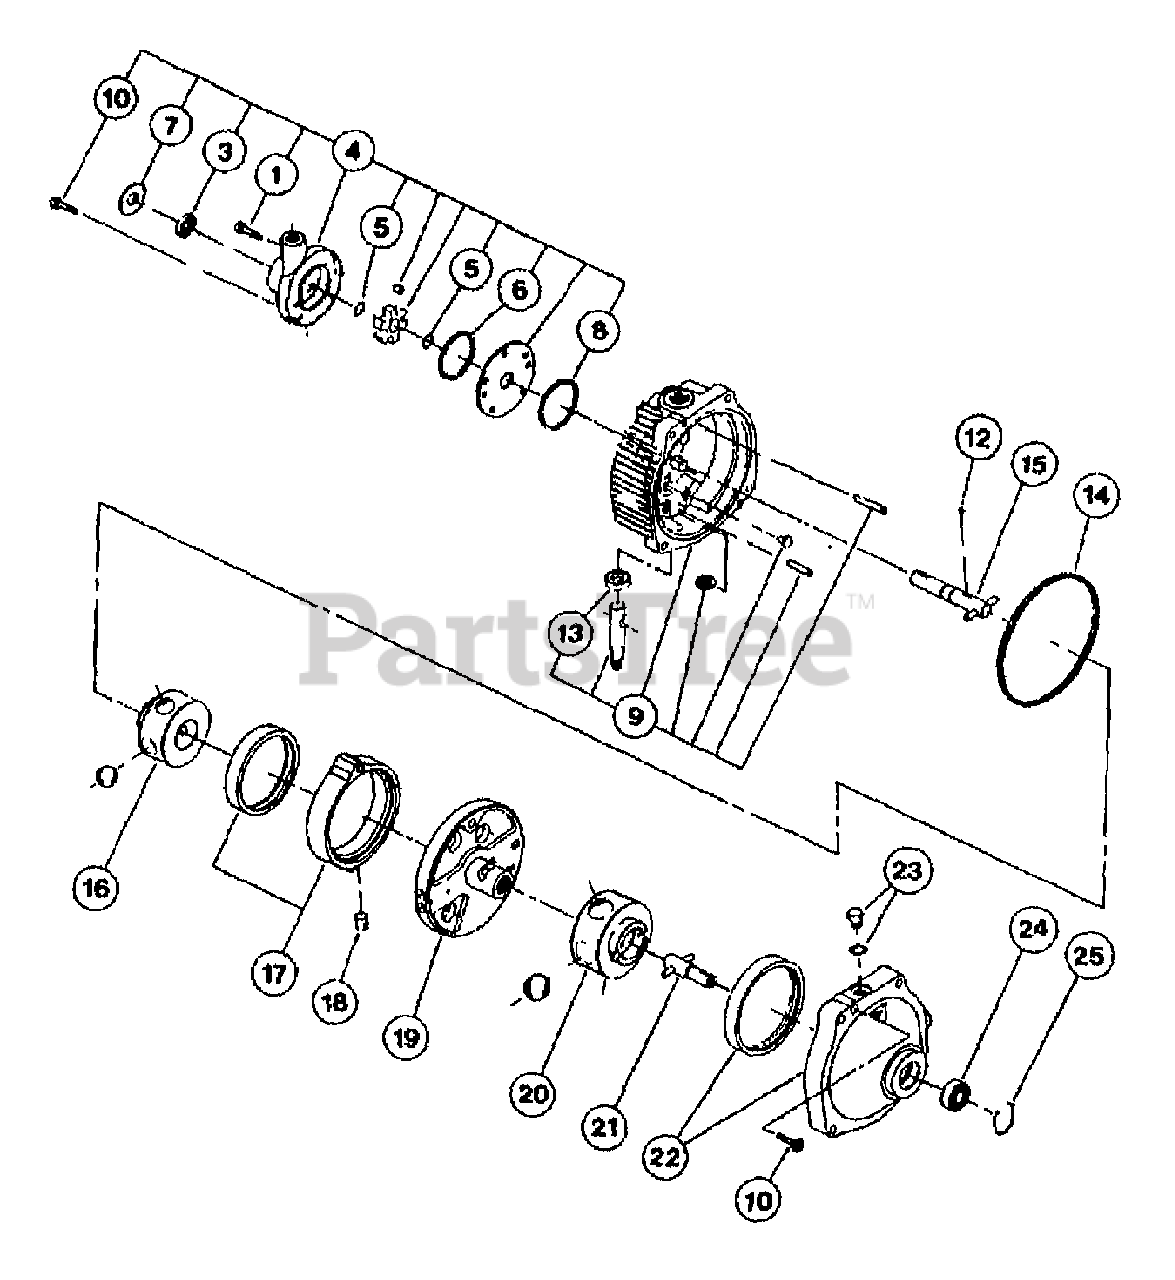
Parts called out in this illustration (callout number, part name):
1	SOCKET HD. CAPSCREW
3	SEAL-OIL
4	KIT-CHARGE PUMP
5	RING-SNAP
6	RING-SQ SEAL
7	SHIELD-GRASS
8	RING-SQ SEAL
9	ASSM-COVER
10	SOCKET HD. CAPSCREW
12	PIN-DRIVE
13	SEAL-OIL
14	RING-SQ SEAL
15	SUBASSM-INPUT SHAFT
16	ASSM-PUMP ROTOR & BALL
17	ASSM-RING CAM
18	RING-CAM INSERT
19	ASSM-PINTLE
20	ASSM-MOTOR ROTOR & BALL
21	SUBASSM-OUTPUT SHAFT
22	ASSM-BODY
23	SUBASSM-O RING PLUG
24	BRG-BALL (OUTPUT)
25	RING-RETAIN
